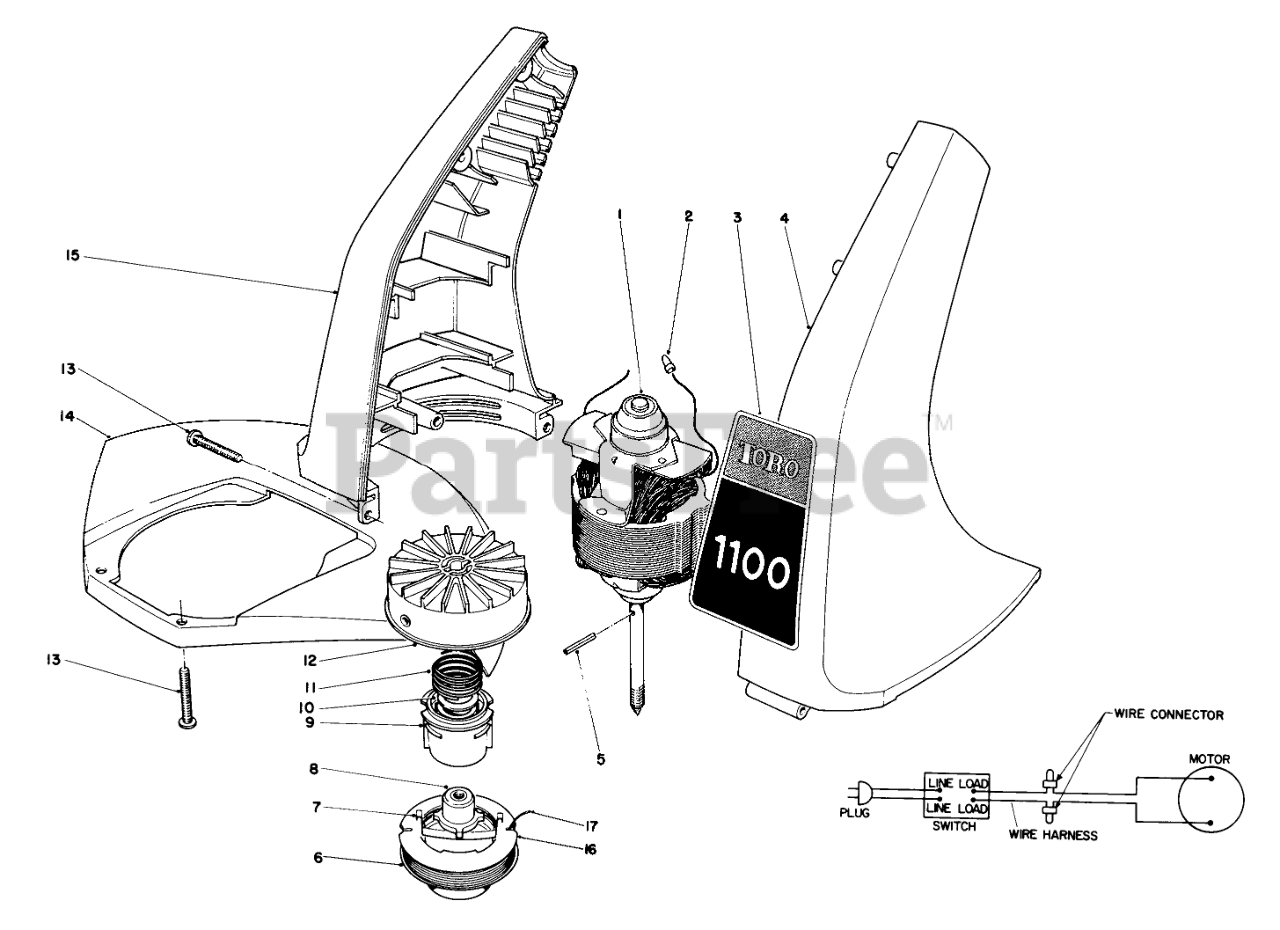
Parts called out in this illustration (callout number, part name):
1	Motor
2	CONNECTOR WIRE JOINT
3	1100 Decal
4	Housing-Left Hand
5	COIL PIN
6	Cutting Line (50 .065" Dia.)
7	SADDLE-SPOOL CAP
8	Driver
9	SPOOL CORE
10	WASHER-FLAT
11	SPRING COMPRESSION
12	DRUM W/EYELET
13	Screw
14	Shield
15	R.H. HOUSING, 1100
16	Empty SPooI
17	LINE-FILIMENT
